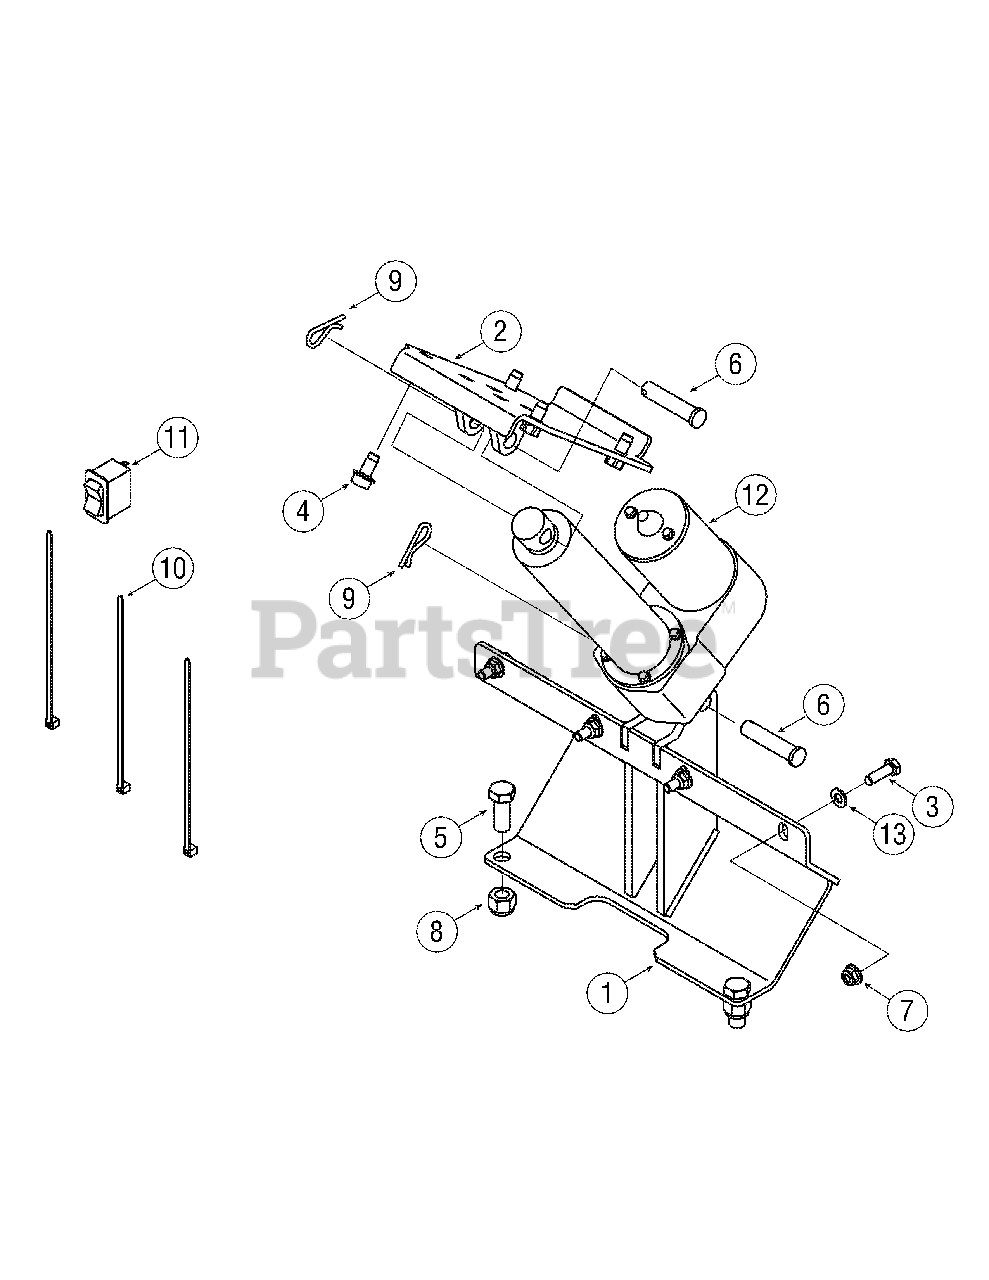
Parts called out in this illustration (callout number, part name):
1	Plate Assembly, Mtg, Bed Lift, Rear
2	Plate Assembly, Bed Lift, Upr
3	Hhcs, 5/16-18 x 1.00
4	Scr., tt, 3/8-16 x .750
5	Hhcs, 1/2-13 x 1.25
6	Pin, Clevis, .5 Dia. X 2.25 Lg.
7	Nut, flglk, 5/16-18
8	Nut, Hexlk, 1/2-13
9	Internal Cotter Pin
10	Tie, Cable
11	Switch, Bed Lift
12	Actr, Linear, Elec Mech
13	Wash, Flat, .330 x .630 x .0635
